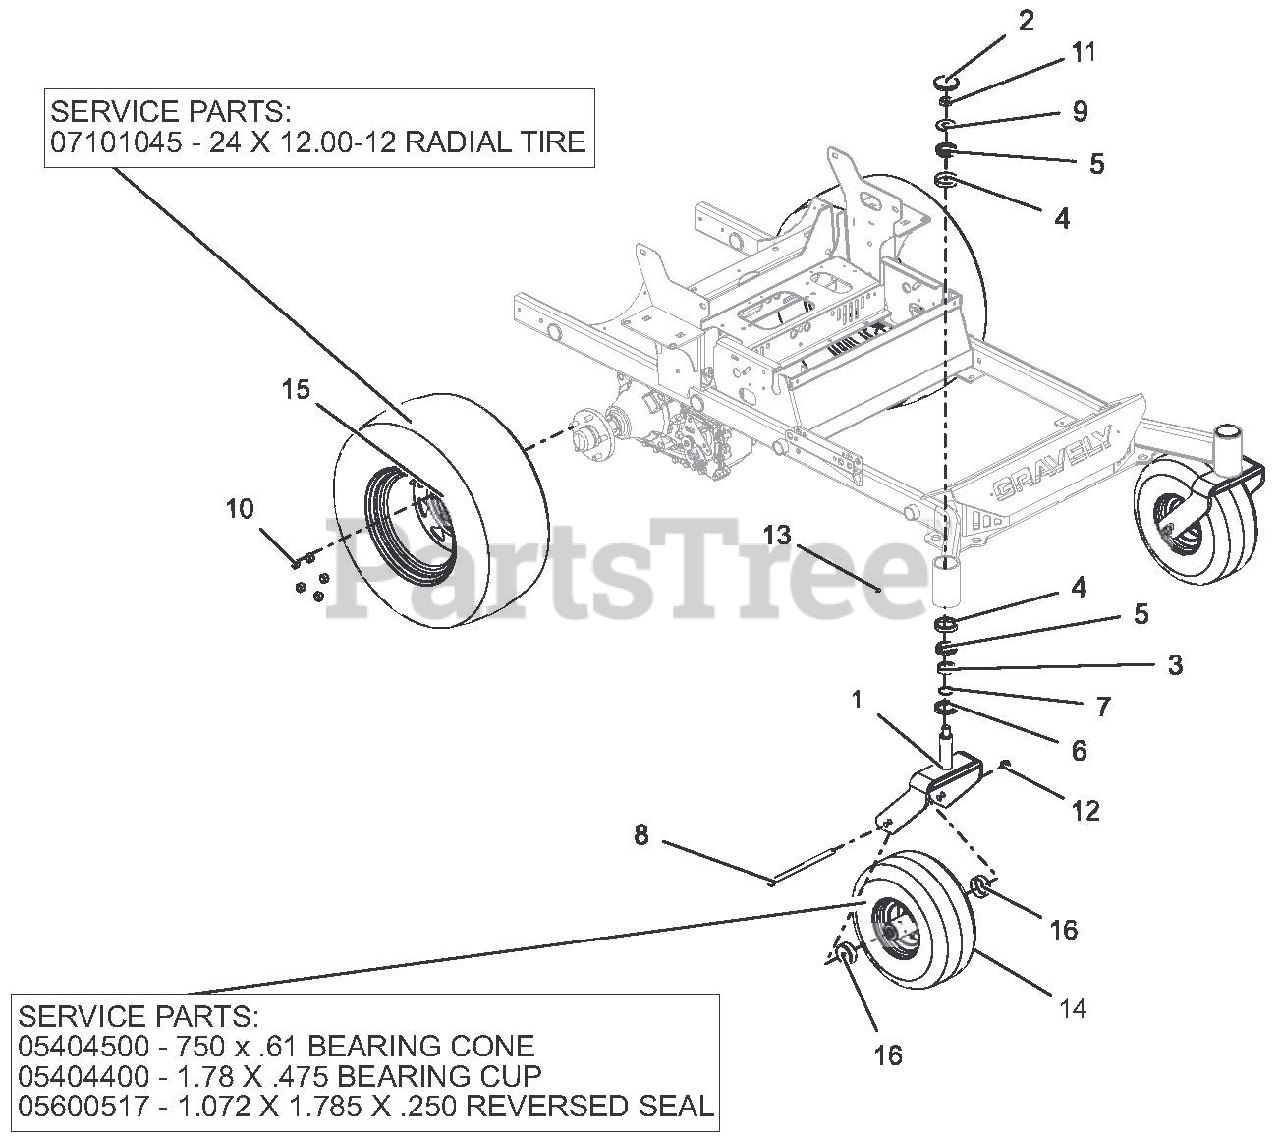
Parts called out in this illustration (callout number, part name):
1	WMT, CASTER FORK
2	CAP, DUST
3	SPCR, FRONT CASTER FOR
4	BRG, CUP 2.328 X .465
5	BRG, CONE 1.250 X .660
6	SEAL, OIL 1.75 X 2.332 X .312
7	O-RING, .139 W X 1.234 ID
8	BLT-HEX .50-13 X 9.00 GR5 YWZC
9	WSHR-FL-STL .812 X 2.00 X .148YWZC
10	NUT, LUG .500-13
11	NUT, JAM TOPLK .75-16 YWZC
12	NUT, LK-TOP-FLG .50-13 YWZC
13	FITTING, .250-28 FLUSH MOUNT GREASE
14	TIRE/WHEEL, 15 X 6.00-6 SEMI-PNEU
14	750 X .61 BEARING CONE
14	1.78 X .475 BEARING CUP
14	1.072 X 1.785 X .250 REVERSED SEAL
15	TIRE/WHEEL, ASM 24 X 12-12 RADIAL
15	24 X 12.00-12 RADIAL TIRE
16	SHIELD, WHEEL BEARING
